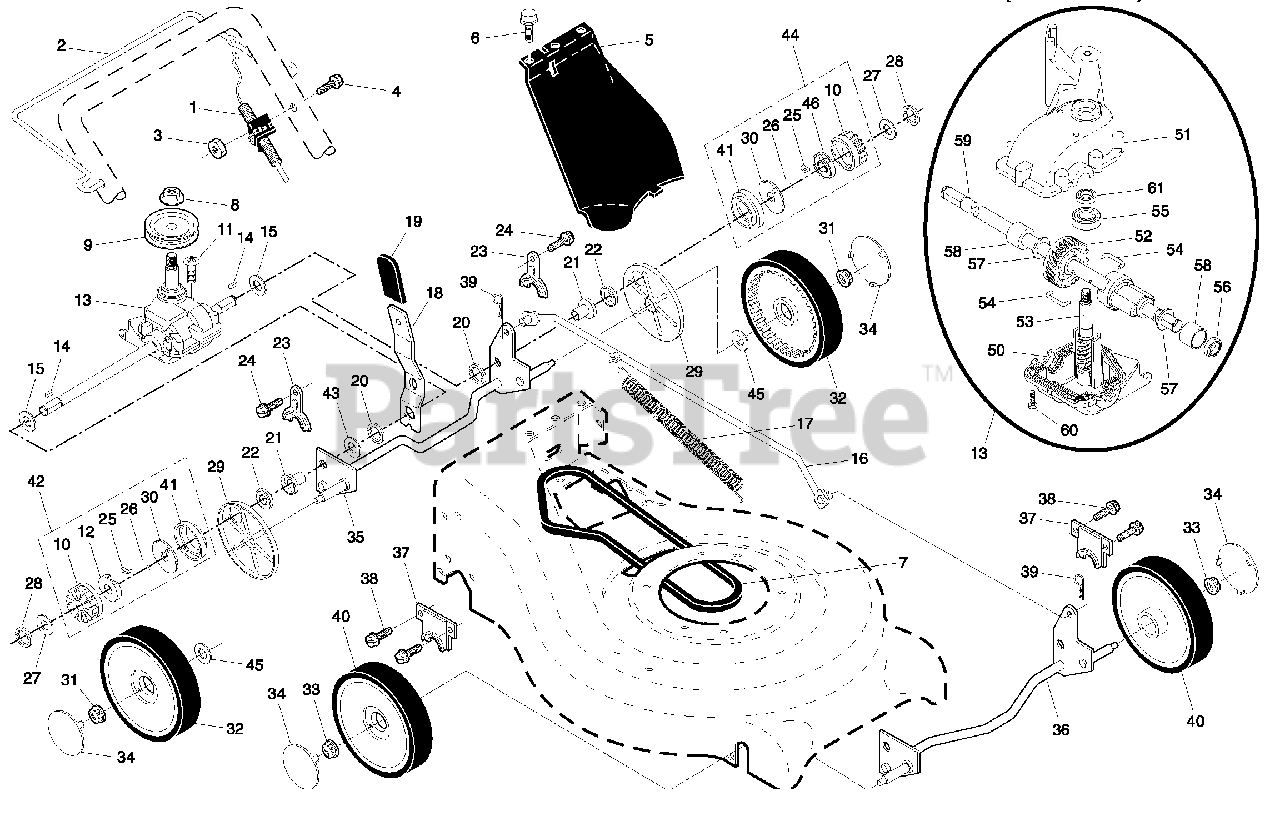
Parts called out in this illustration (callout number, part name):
1	Handle, Upper
2	Handle, Lower
3	Spring, Rear Door, RH
4	Guide, Rope, Side
5	Nut, Hex, with Lockwasher Insert 1/4-20
6	Wire Tie
7	Bolt, Handle 5/16-18 x 2-5/8
8	Knob, Handle
9	Control Bar
10	Pin, Handle
11	Nut, Hex, with Lockwasher Insert 5/16-18 UNC
12	Cotter, Hairpin
13	Spring, Rear Door, LH
14	Screw
15	Bracket, Upstop
16	Rear Door Assembly
17	Bolt, Rear Door
18	Plug, Mulcher
19	Housing Assembly
20	Handle Bracket Asembly, LH
21	Handle Bracket Assembly, RH
22	Screw, Hex Washer Head
23	Bolt, Hex Head 5/16-18 x 5/8
24	Nut, Hex, with Lockwasher Insert 5/16-18
25	Baffle, Side
26	Screw #12 x 5/8
27	Skirt, Rear
28	Screw, Hinge 1/4-20 x 1.25
29	Cable, Engine Zone Control
30	Blade Adapter
31	Blade, 21"
32	Washer
33	Washer, Lock
34	Bolt, Hex Head
35	Debris Shield
36	Bolt
37	Bolt, Engine
39	Grassbag
40	Frame, Grassbag
41	Danger Decal
42	Screw
43	Key, Hi-Pro
44	Pulley
45	Mulcher Door
46	Discharge Deflector
47	Nut, Hex
48	Mounting Bracket, Debris Shield
49	Nut, Hex
50	Screw
51	V-Groove Pulley
52	Nut, Hex, Flanged
53	Locknut, Hex
54	Idler Arm
55	Idler Pulley
56	Bolt, Shoulder, Hex Head
57	Bracket Assembly
57	Operator's Manual, English
57	Operator's Manual, French
57	Repair Parts Manual, English / French
